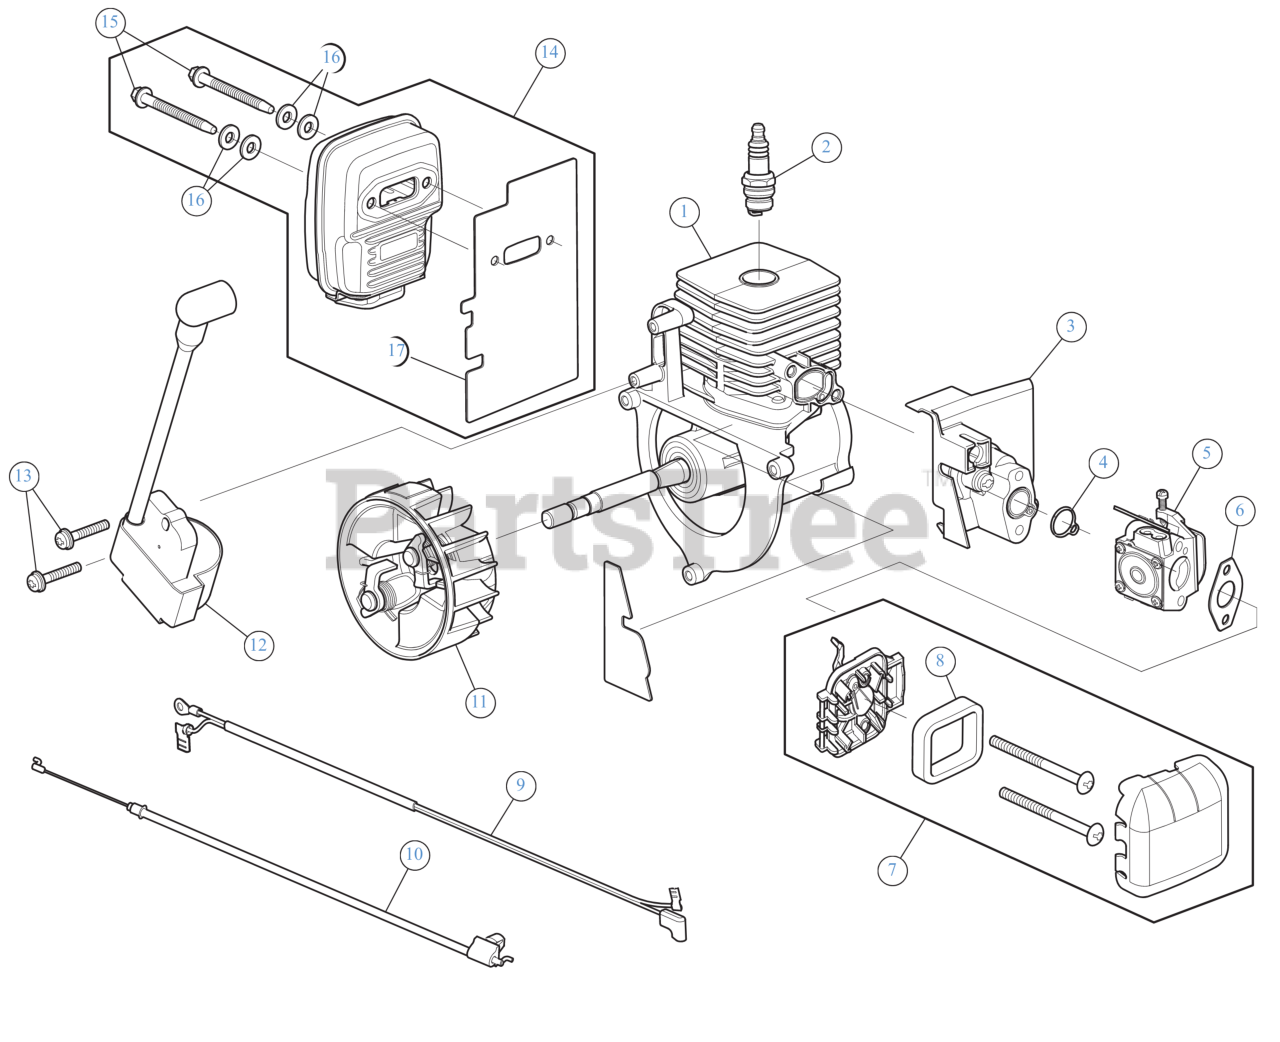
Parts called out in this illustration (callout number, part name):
1	SHORT BLOCK
2	SPARK PLUG
3	INTAKE ASSEMBLY
4	O-RING
5	CARBURETOR
6	GASKET CARB
7	AIR CLEANER ASSEMBLY
8	AIR FILTER
9	WIRE LEAD
10	THROTTLE CABLE
11	FLYWHEEL ASSEMBLY
12	MODULE
13	SCREW 8-32X.750
14	MUFFLER ASSEMBLY
15	MUFFLER SCREW
16	WASH, FLAT .480X.1
17	GASKET
